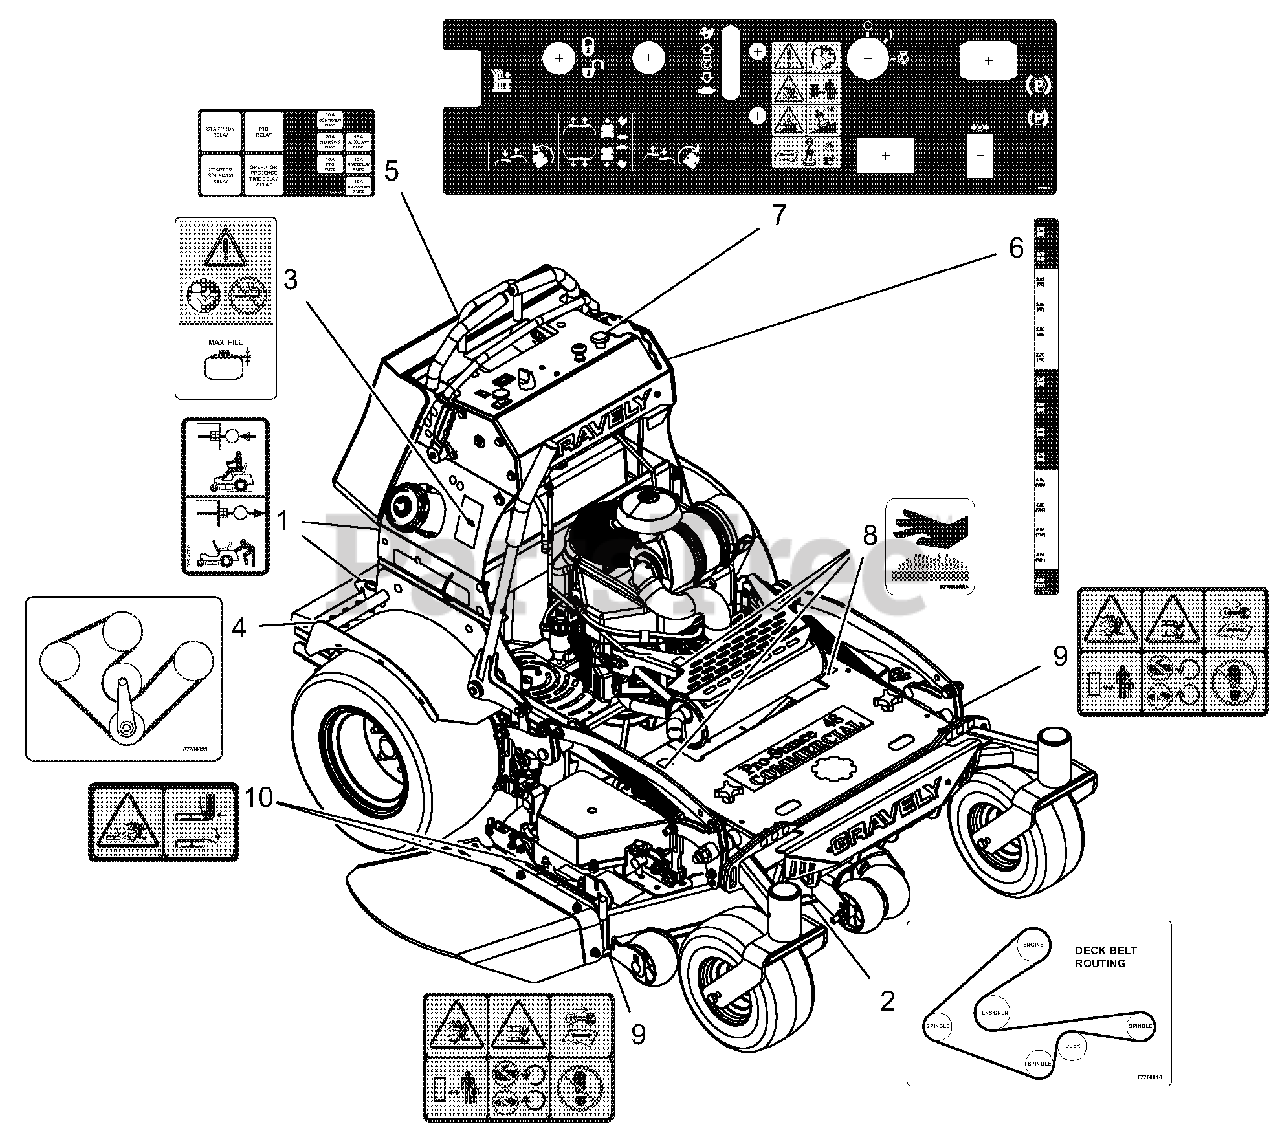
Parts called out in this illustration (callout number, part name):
1	DECAL, TRANSMISSION DISCONNECT
2	DECAL, BELT ROUTING 48/52 REV
3	DECAL, FUEL Warning
4	DECAL, HYDRO BELT (PROSTANCE)
5	DECAL, FUSE BLOCK
6	DECAL, HEIGHT OF CUT - PROSTANCE
7	DECAL, CONTROL PANEL
8	DECAL HOT SURFACE
9	DECAL, SAFETY - MOWER DECK
10	DECAL, SAFETY - DECK GUARDING
